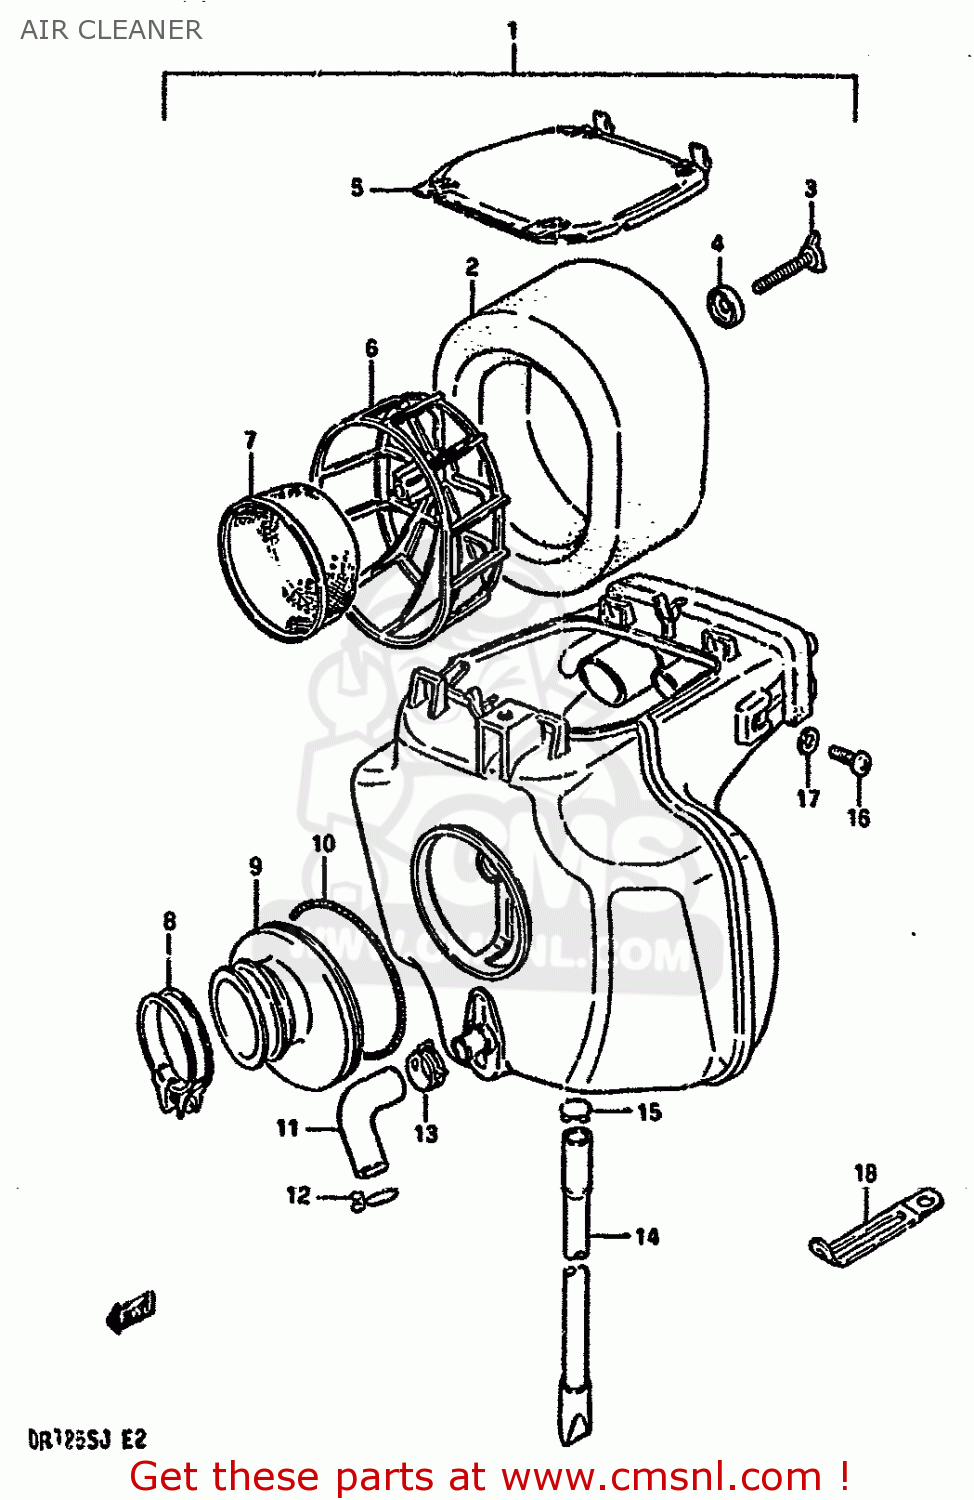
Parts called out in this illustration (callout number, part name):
1	CLEANER ASSEMBLY,AIR
2	FILTER,AIR CLEANER
3	BOLT,WING
4	WASHER,FILTER HOLDER
5	CAP
6	HOLDER,FILTER
7	TRAP
8	CLAMP
9	TUBE,AIR CLEANER OUTLET
10	CLAMP,AIR CLEANER SIDE
11	TUBE,BREATHER
12	CLIP,BREATHER TUBE
13	CLIP
14	DRAIN TUBE
15	CLIP
16	SCREW
17	WASHER,LOCK
18	CLAMP
